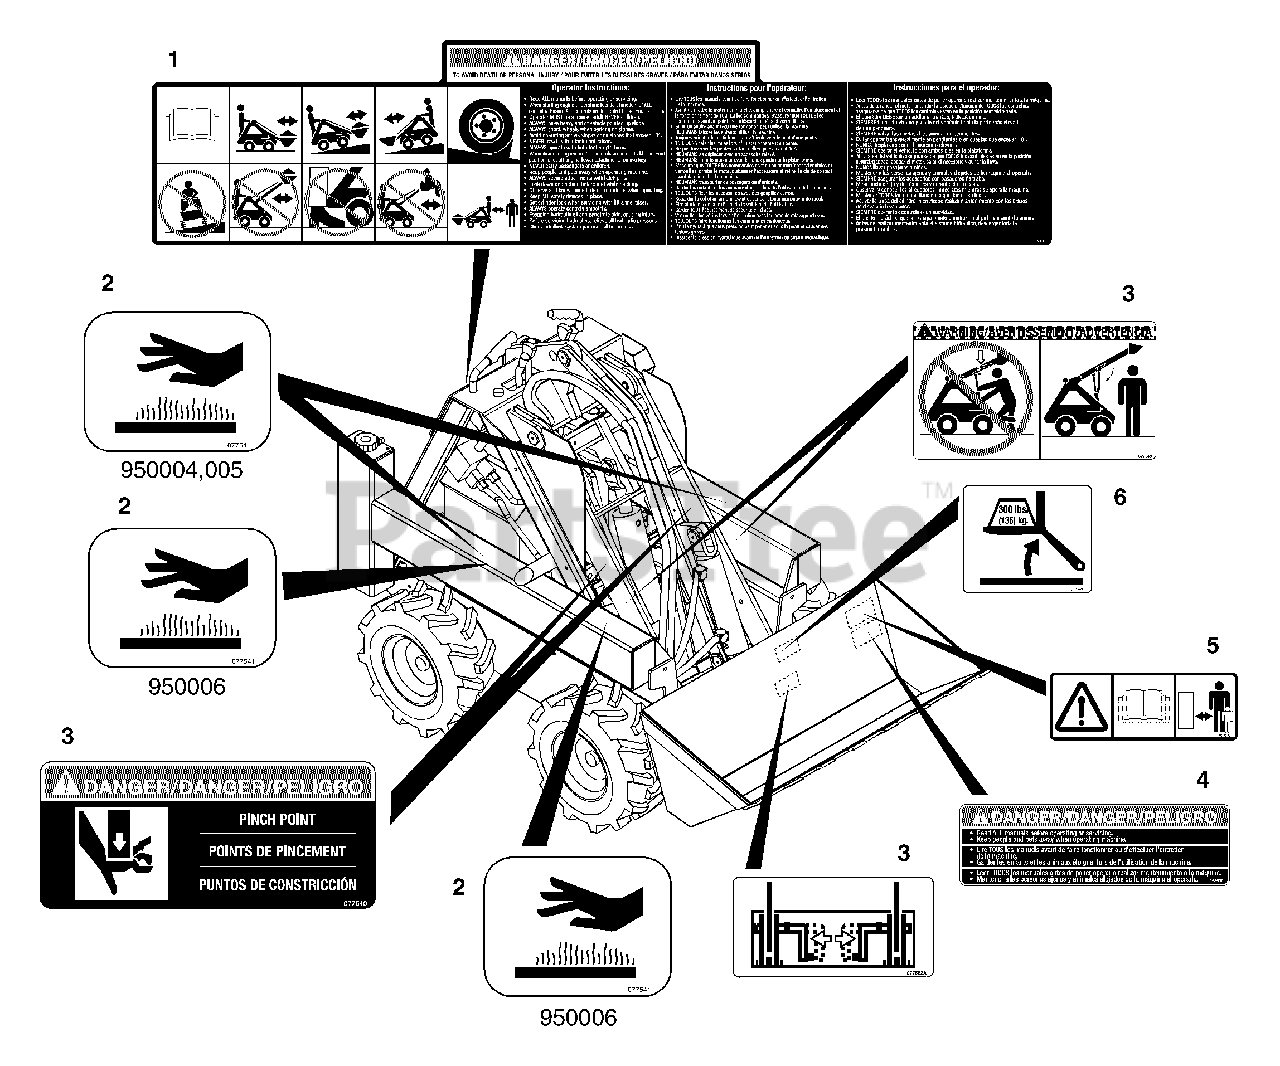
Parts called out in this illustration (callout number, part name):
1	Decal, Operator Safety Instruction
2	Decal, Hot Surface
3	Decal Set, Skidster Safety
4	Decal, Attachment Universal
5	Decal, Attachment Universal
6	Decal, Weight Capacity
